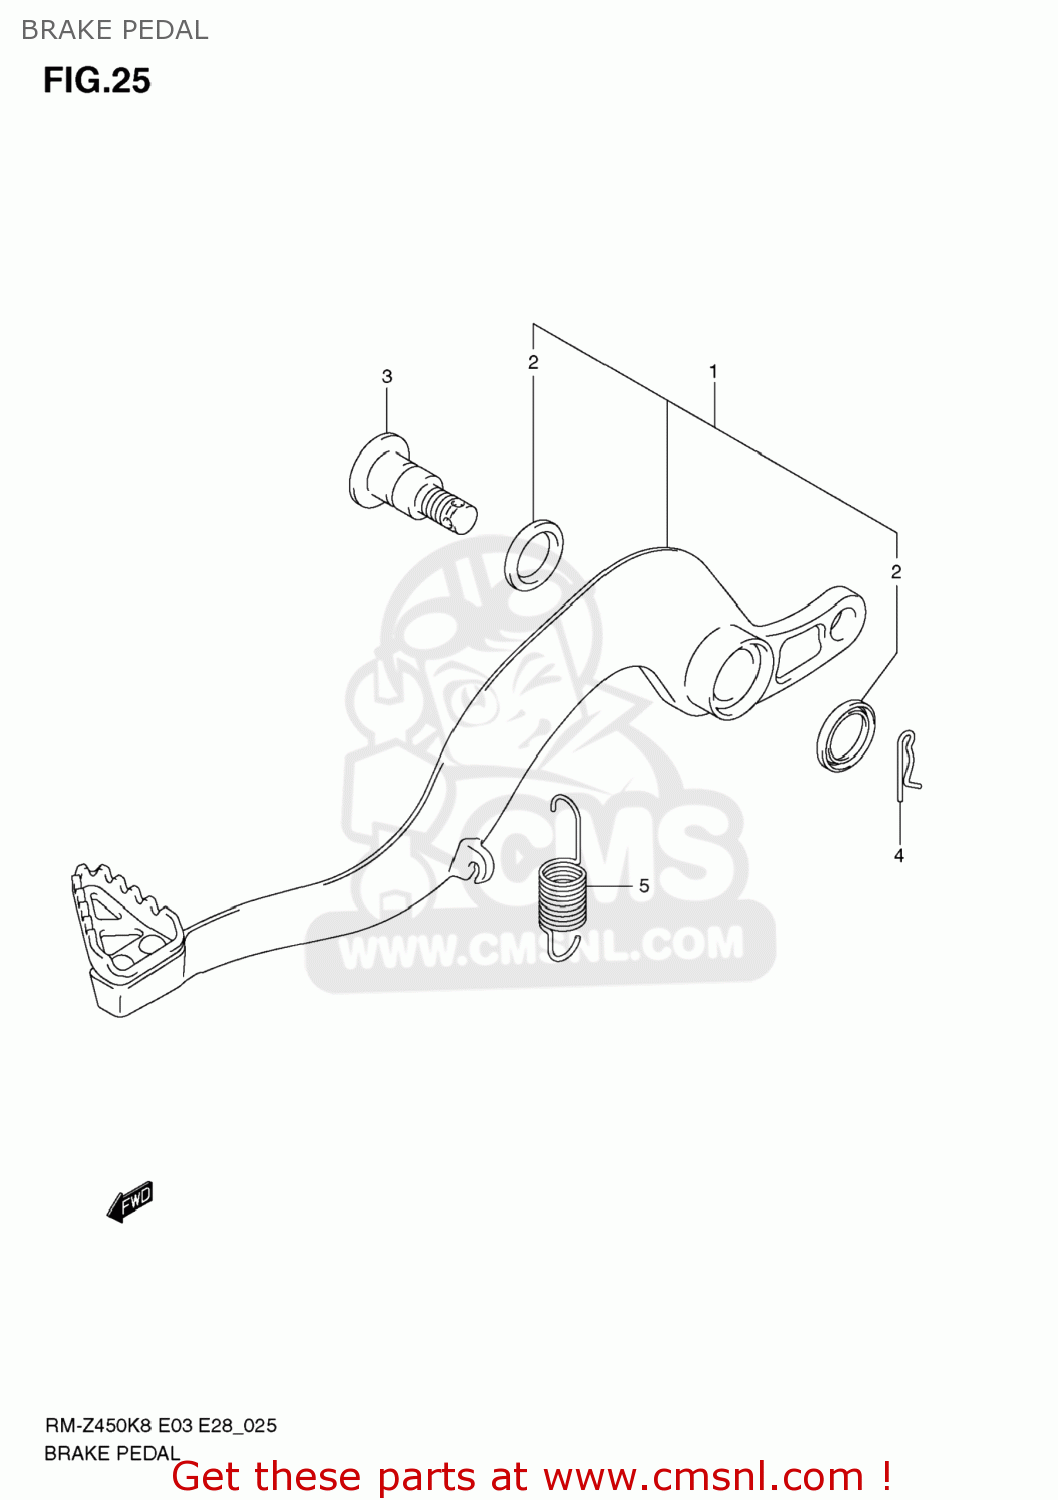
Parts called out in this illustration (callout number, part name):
1	PEDAL ASSY,BRAKE
2	SEAL,OIL(15X21X3)
3	SHAFT,BRAKE PEDAL
4	CLIP
5	SPRING
